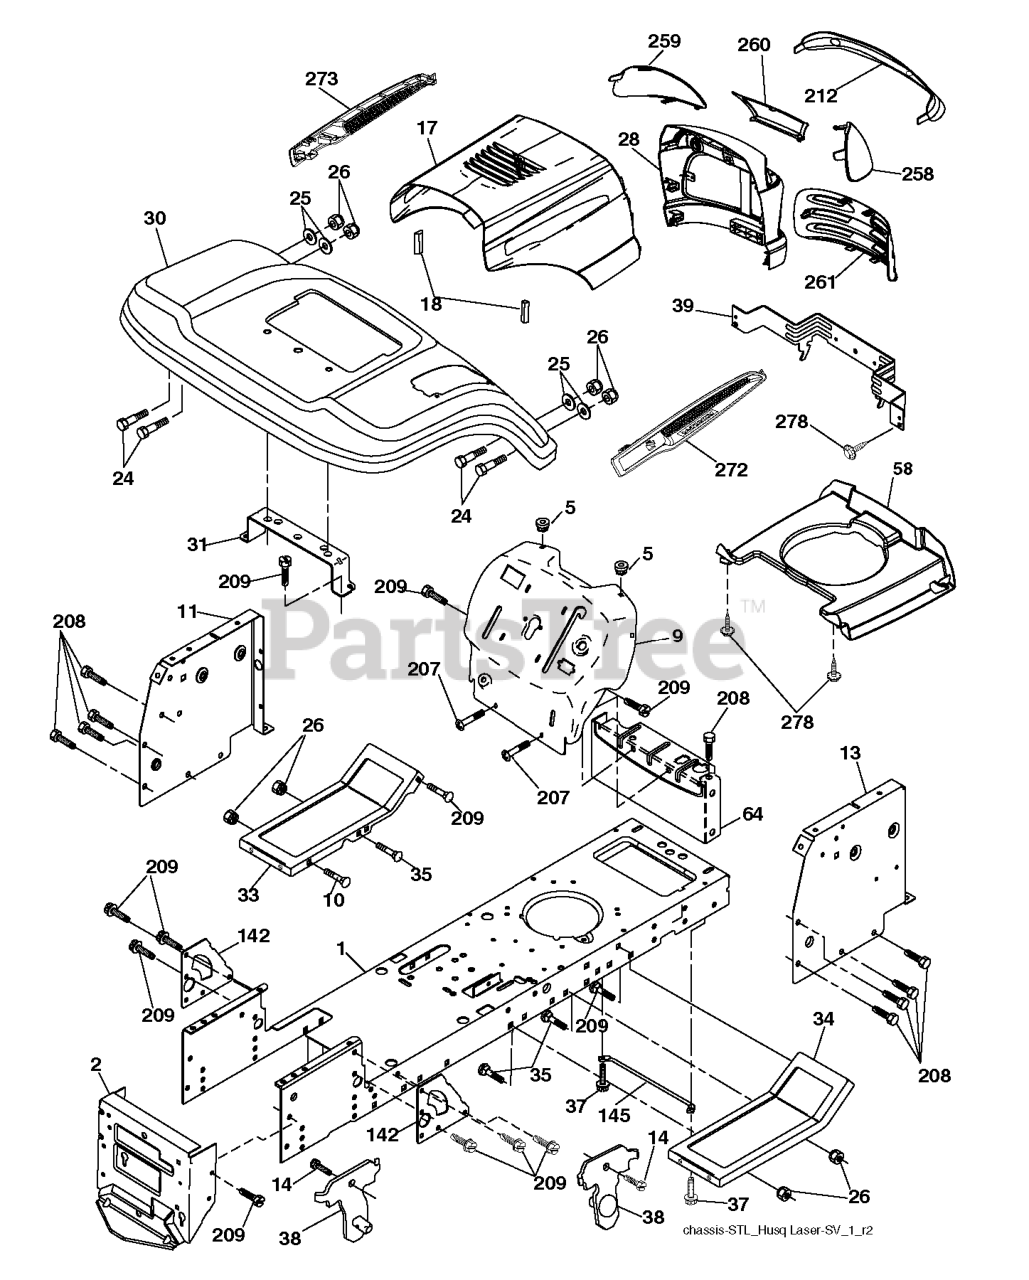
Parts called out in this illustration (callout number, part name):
1	CHASSIS STAMPING
2	DRAWBAR, 12GA
5	BUMPER.RUBBER.HOOD
9	DASH.SLKSCR.SL.PL.C.NA.NHMHUS
10	BOLT D
11	PANEL.DASH.LH.LTX
13	PANEL DASH RH
14	SCREW LT
17	VENT.HOOD.LASER.III
18	BUMPER.HOOD.LARGE.1.75"
24	BOLT
25	WASHER
26	NUT
30	FENDER.PNT.LTST.W/S.N/C.422ROS
31	BRACKET FENDER
33	FOOTREST.PNT.LH.BLACK
34	FOOTREST, RH
35	BOLT
37	Screw 5/16-18 x 1/2 Hex, Self Tapping 5/16-18 x 1/2
38	BRACKET.ASM.PIVOT.MOWER.REAR
39	BRACKET PIVOT
64	DASH LOWER
142	PLATE REINFORCEMENT
145	ROD.PIVOT.HOOD
207	SCREW, 5/16-18 X 1/2
208	SCREW 3/8-16X1/2
209	SCREW, 3/8-16X3/4
212	INSERT.LENS.REFLECTIVE
258	LENS LH
259	LENS LH
260	COVER.LENS.HUSQ.LASER
272	VENT.HOOD.LASER.
273	VENT.HOOD.LASER.
278	SCREW.#10 X 0.750.BOS
